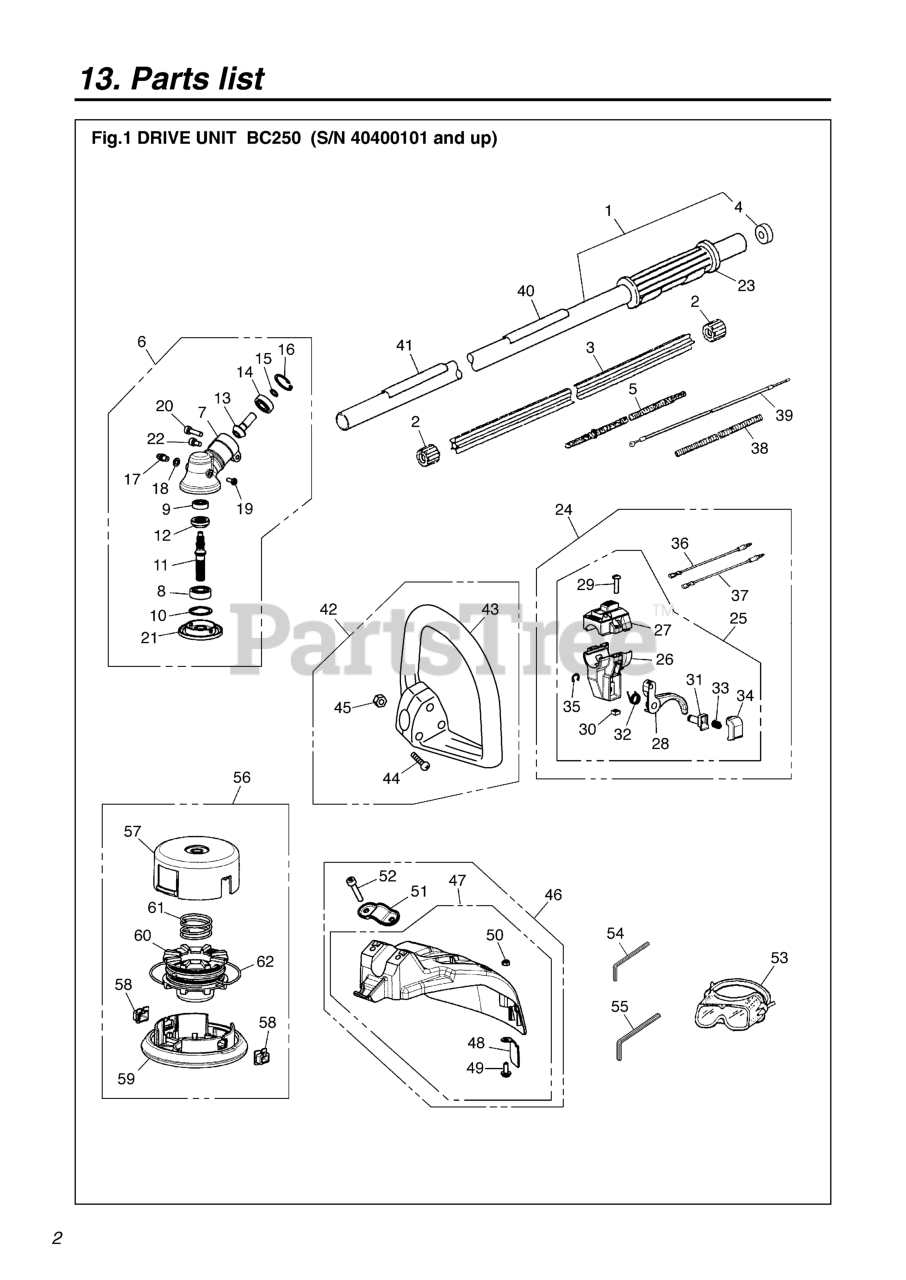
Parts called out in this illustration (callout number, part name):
1	PIPE
4	SEAL
5	SHAFT
6	GEARCASE ASSY.
7	GEARCASE
8	BEARING
9	BEARING
10	SNAP RING
11	SHAFT
12	GEAR
13	PINION
14	BEARING
15	SNAP RING
16	SNAP RING
17	FITTING, GREASE
18	WASHER, FITTING
20	BOLT TORX
21	HOLDER (A)
22	BOLT TORX
23	GRIP
24	LEVER COMP.
25	LEVER (USE 848-8R2-0313)
27	COVER
28	LEVER
36	CORD (A), BLACK
37	CORD (B), RED
39	CABLE COMP
40	LABEL, NAME
41	LABEL, CAUTION
42	HANDLE ASSY.
44	SCREW, M5 x 30
45	NUT
46	GUARD ASSY
47	GUARD COMP.
48	BLADE
49	SCREW TORX
50	NUT
51	CLAMP
52	BOLT, M6 x 1.30
53	GOGGLE
54	WRENCH (T20)
55	WRENCH(T25)
56	TAP HEAD COMP.
57	CASE
58	EYELET
59	COVER
60	CORD HOLDER
61	SPRING
